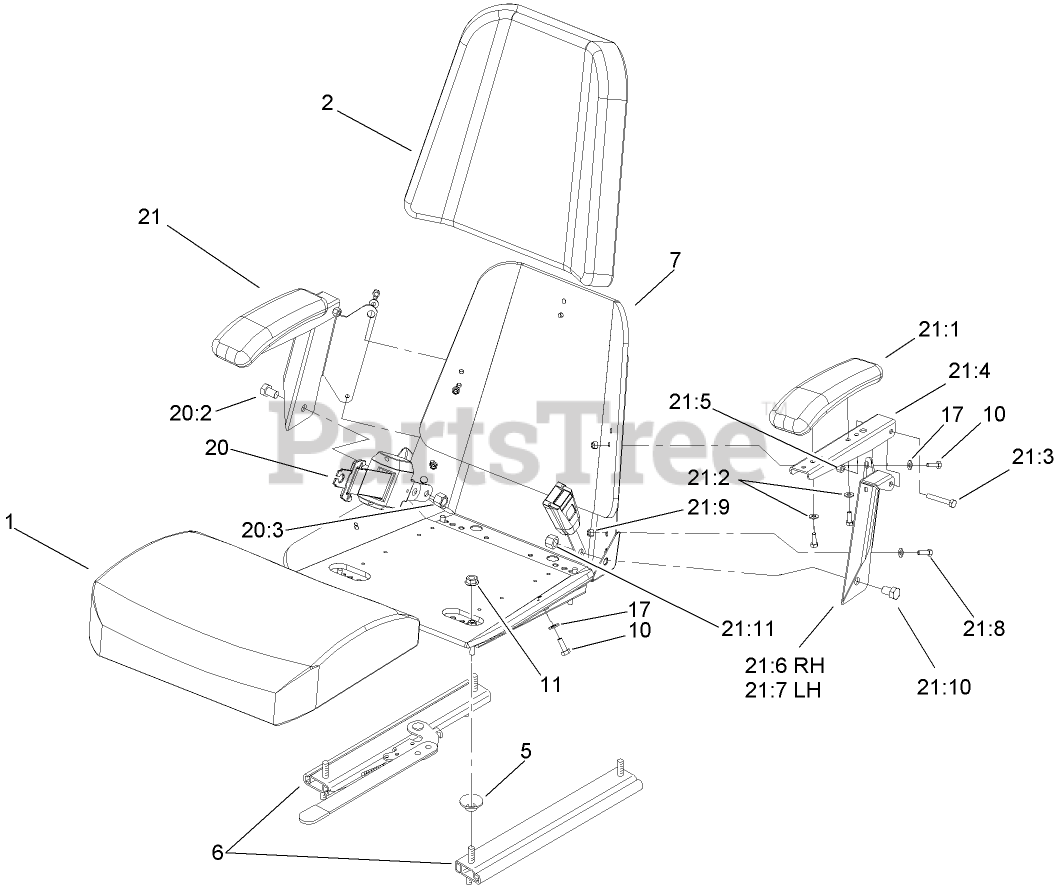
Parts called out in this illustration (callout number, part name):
1	CUSHION-SEAT, BOTTOM
2	CUSHION-SEAT, BACK
5	SPACER-TRACK
6	TRACK-SEAT
7	FRAME-SEAT
10	SCREW-HH
11	NUT-HF
17	WASHER-FLAT
20	RETRACTABLE SEATBELT KIT
20:2	SCREW-HH
20:3	NUT-LOCK
21	ARMREST KIT
21:1	CUSHION-REST, ARM
21:2	WASHER-FLAT
21:3	SCREW-HH
21:4	CHANNEL-ARMREST
21:5	NUT-HEX, SIDE DEFORM
21:6	Bracket-Armrest, RH
21:7	Bracket-Armrest, LH
21:8	SCREW-HH
21:9	NUT-LOCK, NI
21:10	SCREW-HH
21:11	NUT-LOCK, NI
